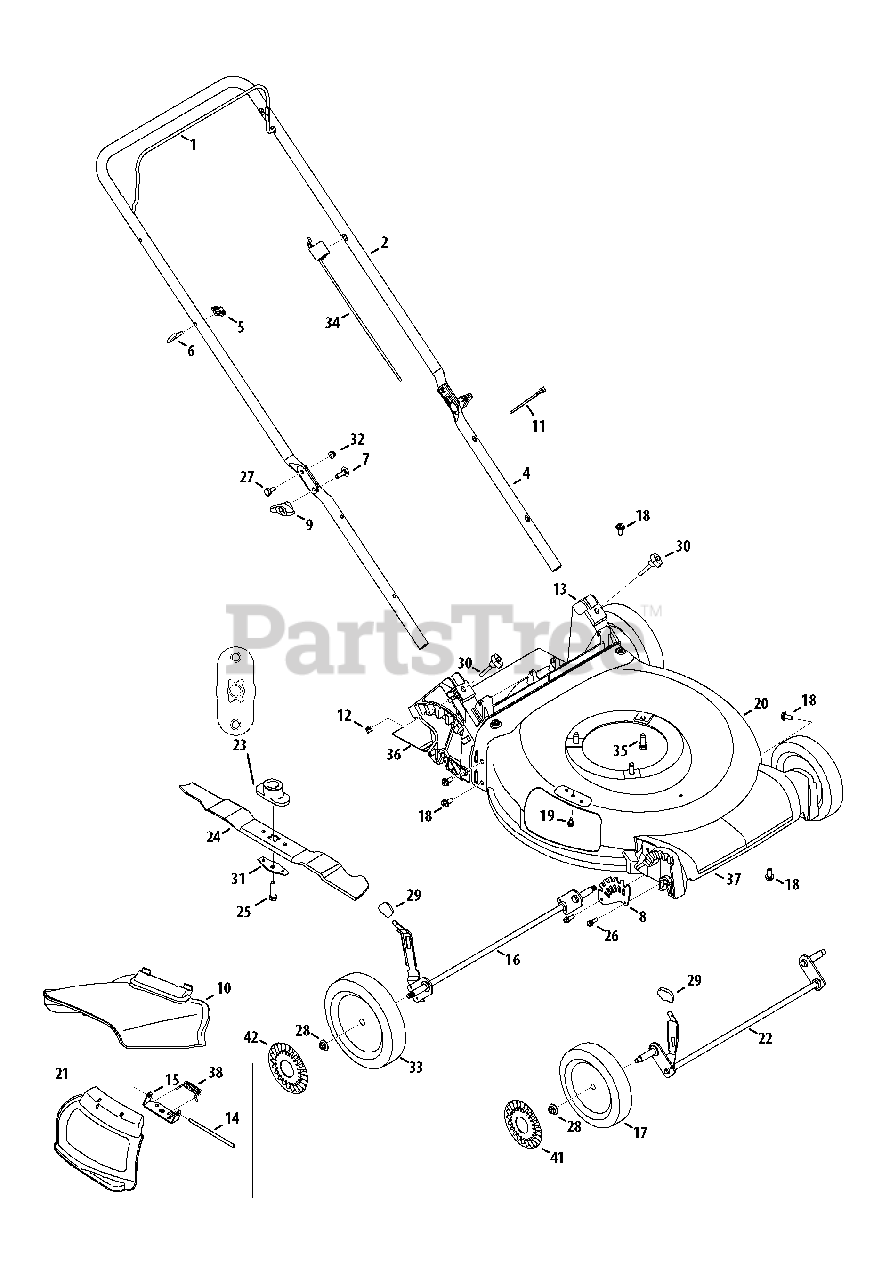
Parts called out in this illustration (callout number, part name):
1	Blade Control Handle - Black
2	Upper Handle - Black (adjustable)
4	Lower Handle
5	Knob 1/4-20
6	Rope Guide Bolt
7	Carriage Bolt 5/16-18
8	Front Height Adjustment Plate
9	Wing Knob 5/16-18 Black
10	Chute Deflector (w/clip)
11	Cable Tie
12	Sq. Nut 1/4-20
13	Rear Baffle
14	Hinge Pin
15	Chute Deflector Bracket
16	Rear Axle Ass’y - 8" wheel
17	Wheel Ass’y 7 x 2.0 Sleeve Zag Black
18	Hex Hd. Cap Scr. 5/16-14 x .75
19	Sems TT Scr. 1/4-20 x .50
20	21" Deck Ass’y
21	Hinged Mulch Plug Ass’y
22	Front Axle Ass’y - 7 " wheel
23	Blade Adapter (25 mm x 1.19)
24	21" Mulching Blade
25	Hex Bolt 3/8-24 x 1.5" Lg. (Gr 8)
26	Screw, 1/4-15 x .750
27	Shoulder Screw .375 x .126 x 1/4-20
28	Flange Locknut 3/8-16 Gr. F Nylon
29	Knob (Black)
30	Knob 1/4-20 x 1.725 Black
31	Blade Bell Support
32	Flanged Lock Nut 1/4-20 Gr. F Nylon
33	Wheel Ass’y 8 x 2.0 Sleeve Zag Black
34	Control Cable, 160 cc Honda
35	Hex Wash HD Tap Scr 3/8-16 x 1.0
36	Trailing Shield 4.54 x 17.37
37	Front Axle Cover
38	Torsion Spring
41	Hub Cap (7")
42	Hub Cap (8")
